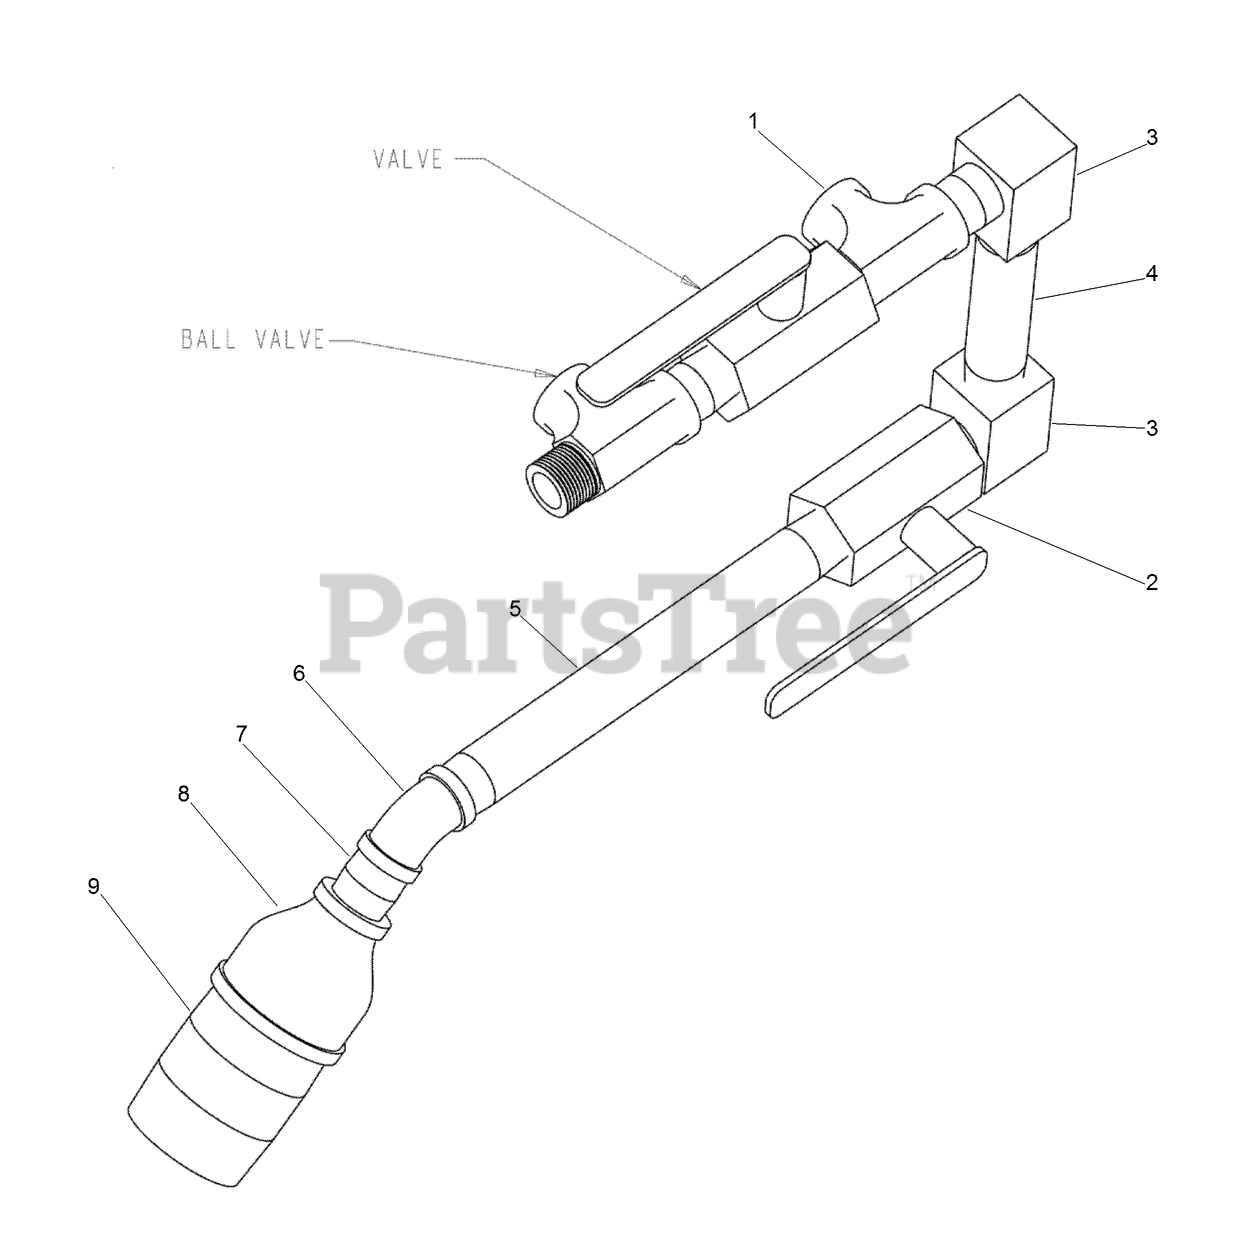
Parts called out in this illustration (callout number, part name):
1	TEE - Pipe, Plated Stl 3/4, 2-Female, 1-Male
2	VALVE-BALL
3	ELBOW - 90 Deg 3/4 NPTF Male / Female M.I. Blk
4	NIPPLE - Pipe 3/4 NPTF x 5.00 Black Stl
5	NIPPLE-PIPE
6	ELBOW-FEMALE, 45 DEG
7	NIPPLE-STRAIGHT
8	FITTING-BELL REDUCER
9	NIPPLE-PIPE
